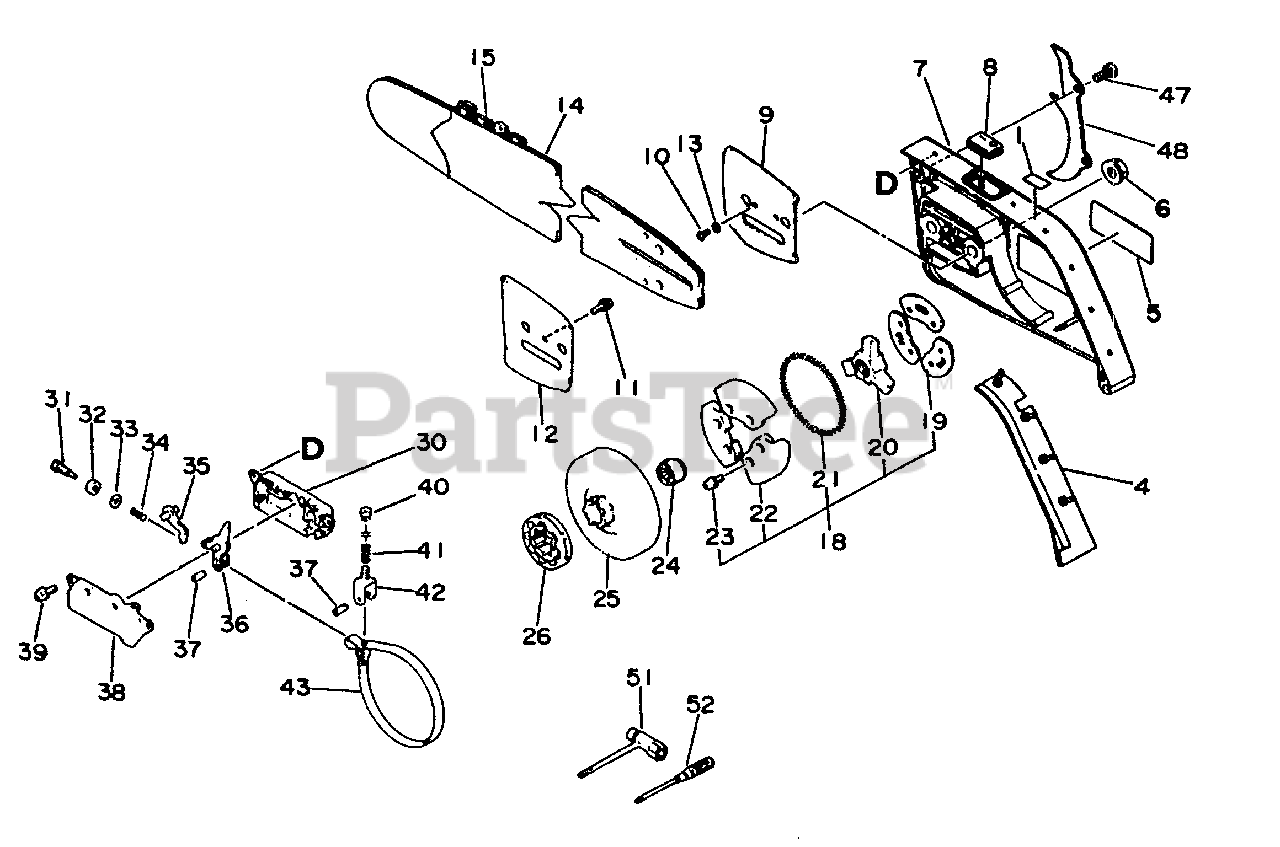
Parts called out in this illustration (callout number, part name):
1	LABEL, CAUTION
5	LABEL - ECHO
6	NUT, FLANGE M8×1.25
7	GUARD, SPROCKET
9	PLATE, GUIDE - OUTER
10	SCREW 3×6
11	SCREW - 4×10
12	PLATE, GUIDE - INNER
14	GUIDE BAR
18	CLUTCH ASSY
19	PLATE, CLUTCH
20	HUB, CLUTCH
21	SPRING, CLUTCH
22	CLUTCH SHOE SET
23	SCREW - 4×8
24	BEARING, NEEDLE
25	DRUM, CLUTCH
26	SPROCKET, RIM 3/8"×7T
30	COVER, BRAKE
34	SPRING ,BRAKE
35	STOPPER, BRAKE
36	LEVER, BRAKE
37	PIN, SPRING
39	SCREW - 4×10
42	ADJUSTER, BRAKE BAND
43	BAND, BRAKE
48	SPIKED BUMPER KIT
51	T-WRENCH 13×19×180
52	SCREWDRIVER, PHILLIPS
